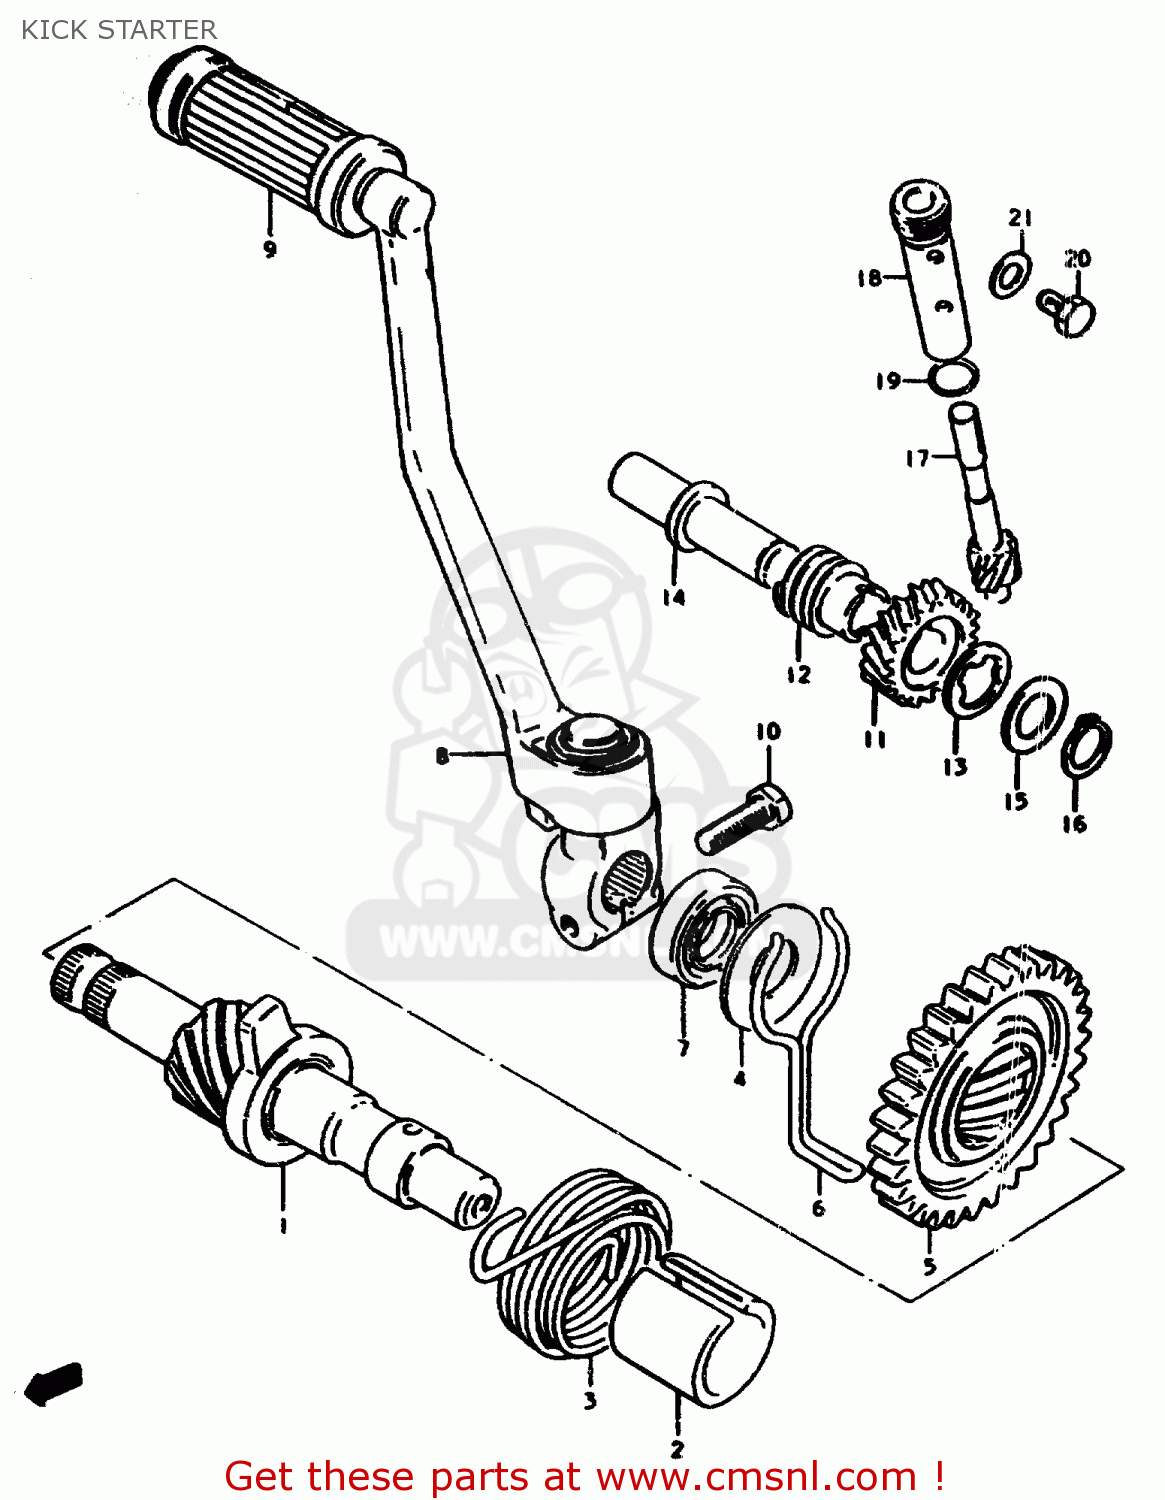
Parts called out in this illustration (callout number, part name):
1	SHAFT,KICK STARTER
2	GUIDE,KICK STARTER SFT SPRING
3	SPRING
4	WASHER
5	GEAR,KICK STARTER DRIVE(NT:30)
6	RETAINER,SNAP
7	SEAL,OIL(14X24X6)
8	LEVER ASSY, KICK STARTER
9	RUBBER,KICK STARTER PEDAL
10	BOLT
11	GEAR, TACHOMETER DRIVE NO.2
12	GEAR,TACH DRIVE NO.2(NT:3)
13	RETAINER,TACH DRIVEN GEAR NO1
14	SHAFT,TACHOMETER DRIVEN GEAR
15	WASHER,THRUST
16	CIRCLIP
17	GEAR,TACHOMETER DRIVEN(NT:12)
18	SLEEVE
19	O RING(D:1.3,ID:9.6)
20	BOLT
21	GASKET(6.2X11X1).2 (NAS)
